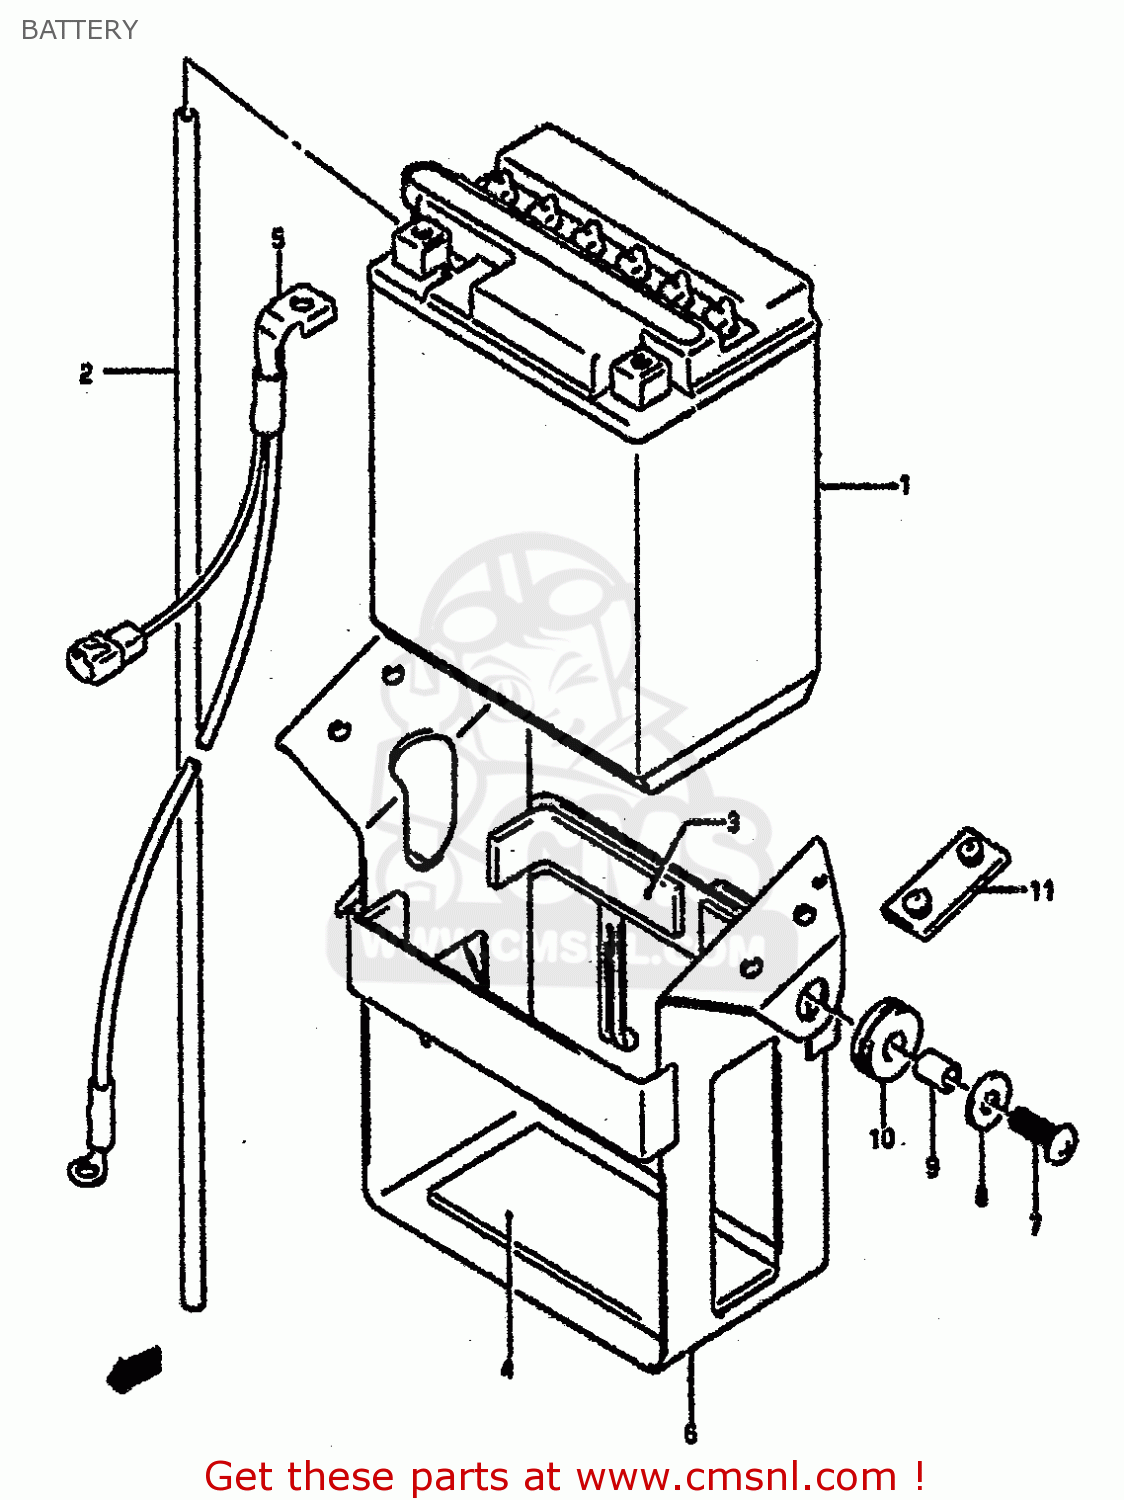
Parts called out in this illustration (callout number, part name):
1	BATTERY ASSY (12V)
2	HOSE,BATTERY EXHAUST
3	PROTECTOR,20X9
4	PROTECTOR(170X95X3.0)
5	WIRE,BATTERY MINUS LEAD
6	HOLDER COMP,BATTERY
7	SCREW
8	WASHER
9	SPACER
10	CUSHION
11	CUSHION
